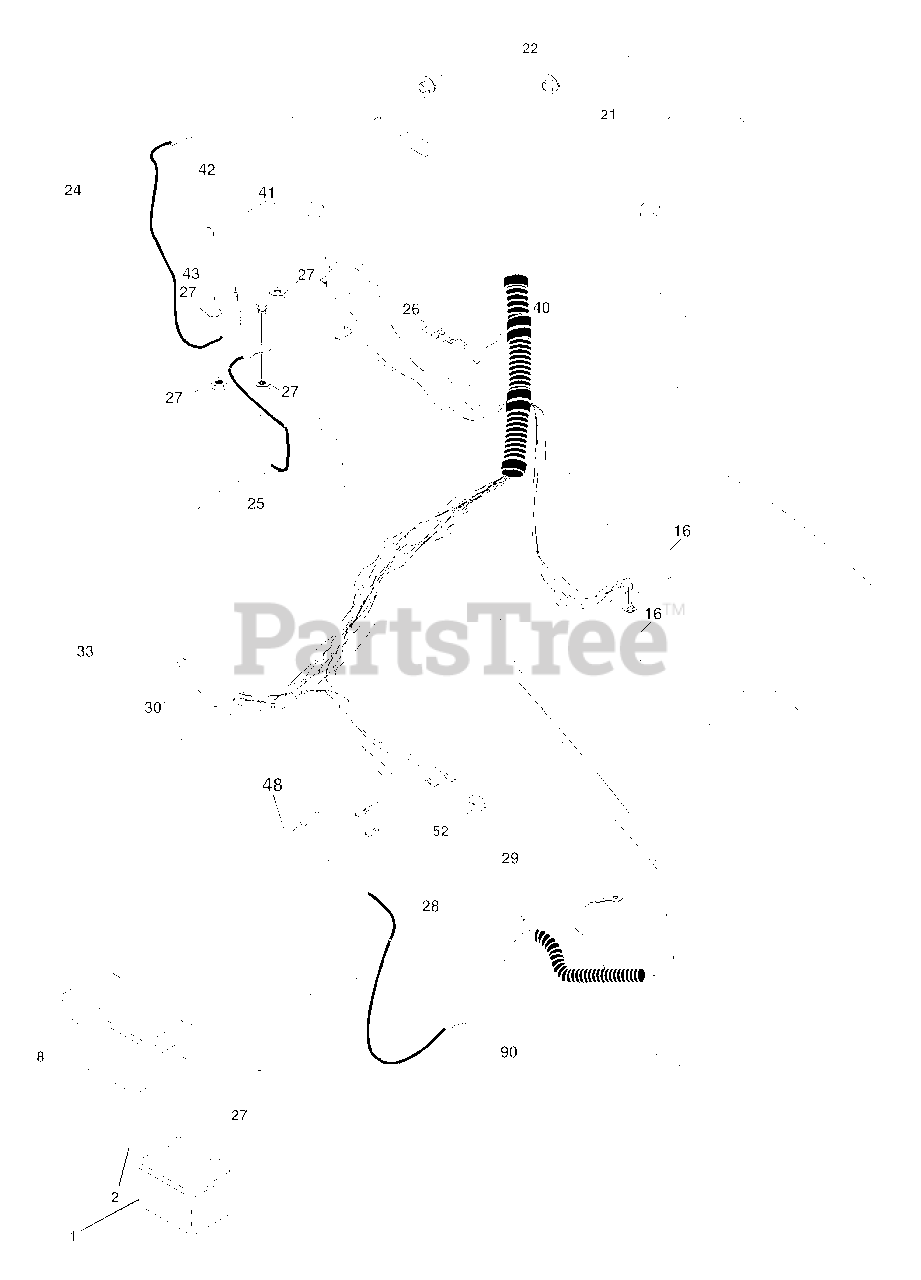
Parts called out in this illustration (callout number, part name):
1	Battery
2	Bolt Hex Hd 1/4-20unc X 3/4
8	Box Battery
16	Switch Interlock
21	Harness Asm Light W/4152j
22	Bulb Light #1156
24	Cable Battery 6 Ga 11" red
25	Cable Battery
26	Fuse 20 AMP
27	Nut Keps Hex 1/4-20 Unc
28	Cable Ground 6 Ga 12" black
29	Switch Plunger Nc Gray
30	Switch Ign
33	Key Ign
40	Harness Ign
41	Bolt Blk Fin Hex 1/4-20
42	Cover Terminal Red
43	Solenoid
48	Adapter Ammeter
52	Protection Wire Loop
90	Cover Terminal Battery
